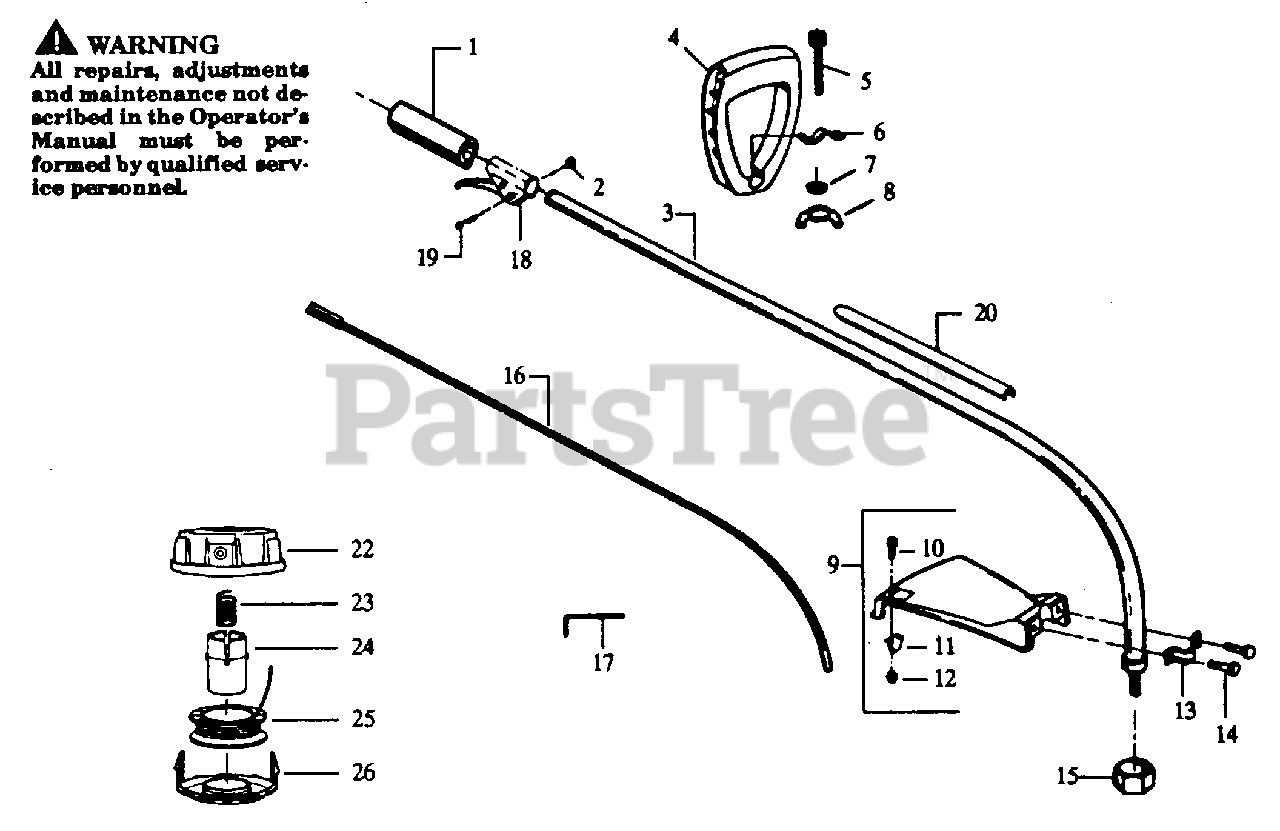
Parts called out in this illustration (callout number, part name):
3	Drive Shaft Housing
4	Handle Ass'y.
9	Shield Kit Ass'y. (Inc.10,11,12,14)
11	Line Limiter
12	Locknut
13	Shield Bracket
14	Screw
15	Dust Cup
16	Drive Shaft
17	Hex Wrench (5/32)
18	Throttle Housing Ass'y.
20	Shaft Warning Decal
22	Hub Ass'y.
24	Release Button
25	Spool w/Line
